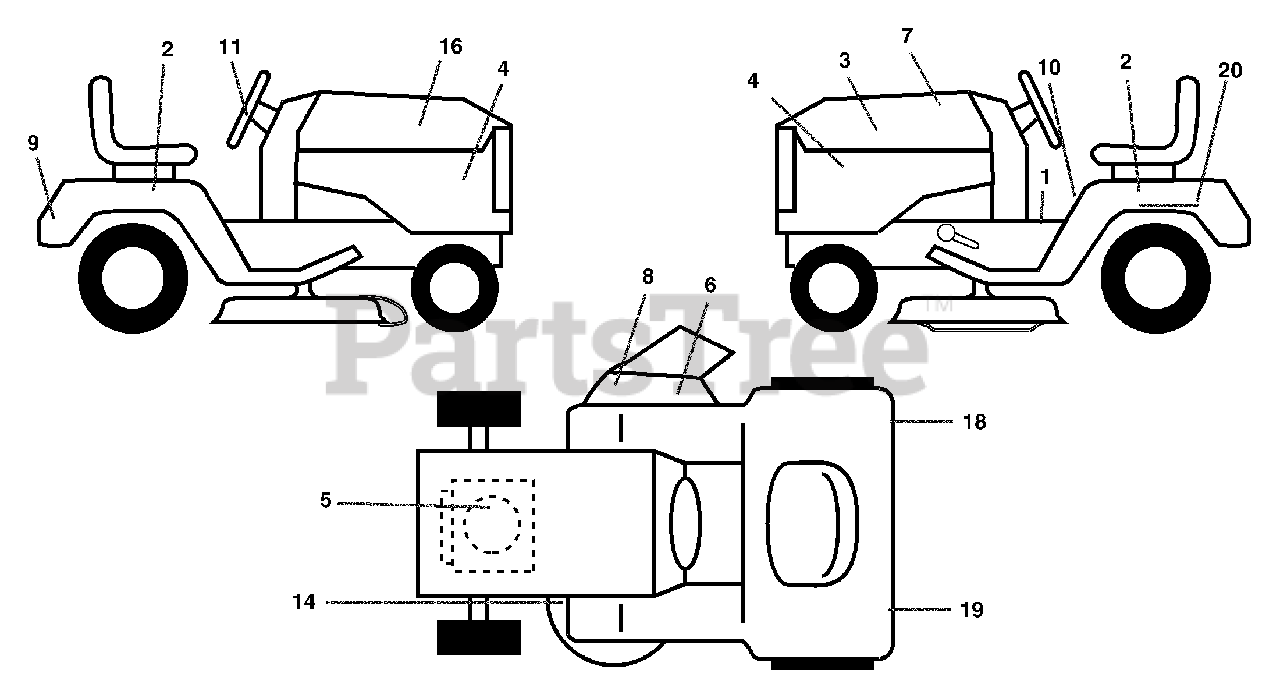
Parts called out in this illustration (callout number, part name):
2	Decal Fender Side
3	Decal Hood LH
4	Decal Side Panel Logo
5	Decal HP Engine
6	Decal Deck "B" 42"
7	Decal Repl. Parts
8	Decal Warning Mult-Language
9	Decal Fender Logo
10	Decal Fender Danger E/F
11	Decal Ins Strg Whl
14	Decal V-Belt Schematic
16	Decal Hood Rh
18	Decal Fender Reflector RH
19	Decal Fender Reflector LH
20	Decal Bat Dan/Psn
